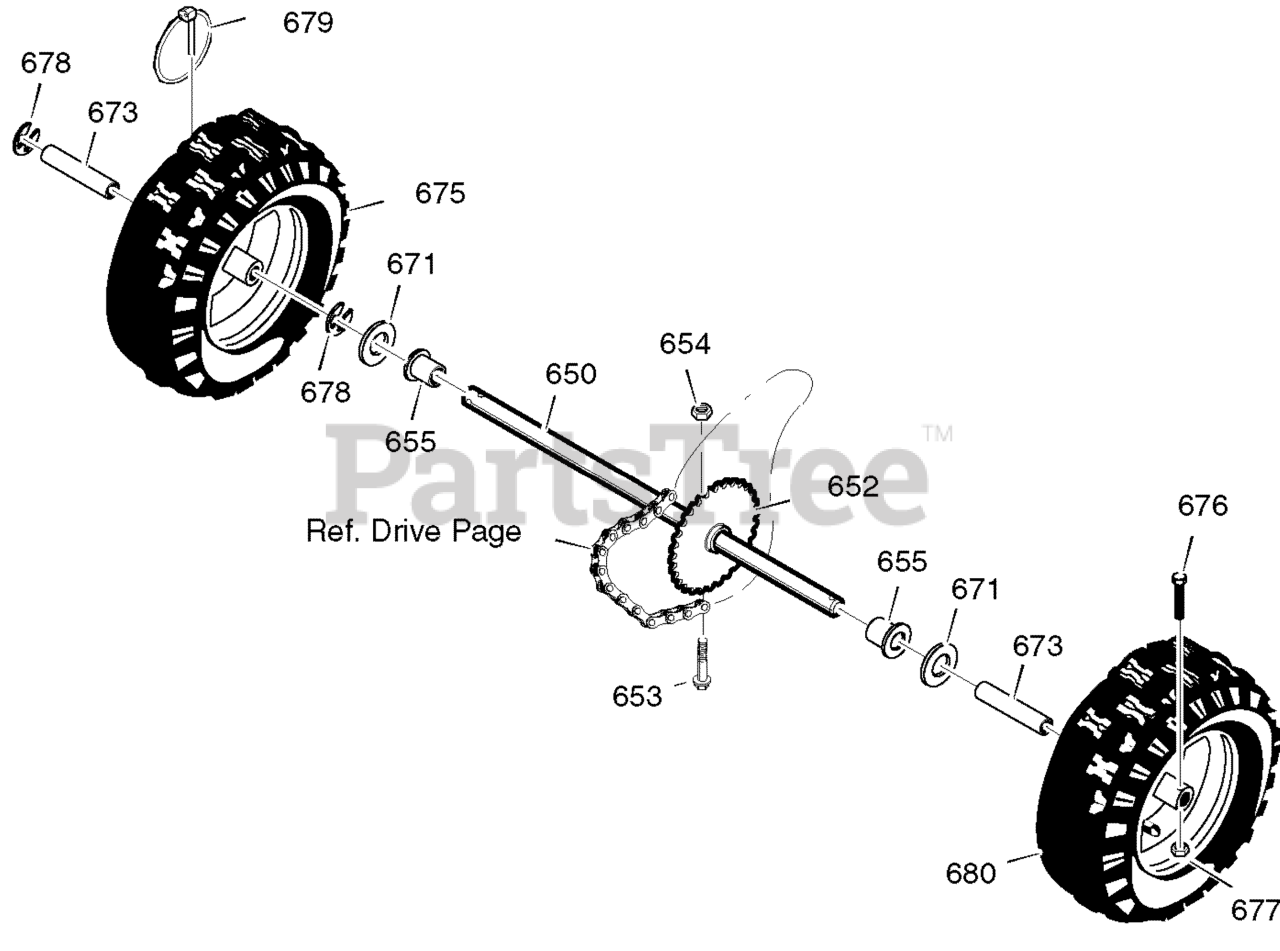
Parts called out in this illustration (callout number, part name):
650	SHAFT, AXLE
652	SPRKT & HUB
653	SCREW, 1/4-20 x 1.75
654	NUT, 1/4-20 HEX NYLOCK YZ
655	BEARING, AXLE
671	WASHER, FLAT
673	BUSHING, WHEEL
675	TIRE & RIM -RIGHT
676	SCREW, 1/4-20X1.75 HH
677	NUT, 1/4-20 HEX NYLOCK YZ
678	RING, RET
679	PIN, KLIK .25 X 1.38 DIA
680	TIRE & RIM -LEFT
